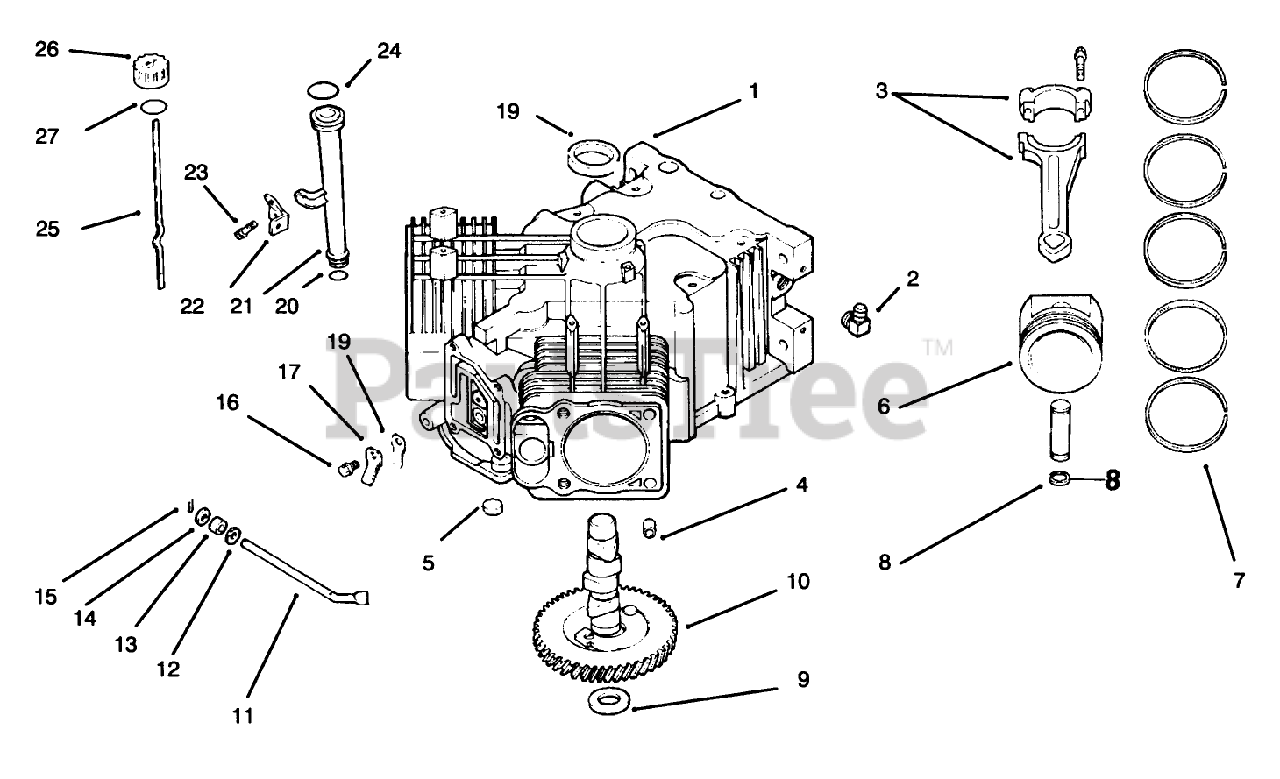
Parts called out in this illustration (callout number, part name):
1	Miniblock
2	Fitting
3	Rod-Connecting (Std)
4	Pin-Dowel
6	Piston w/Ring Set (Std.) (Incl. Ref. # 4-6)
7	Set-Ring (Std)
8	Retainer-Piston Pin
9	Shim-Camshaft
10	Camshaft
11	Shaft-Governor Cross
12	Washer
13	Seal
14	Washer
15	Pin-Hitch
17	Retainer-Reed (Only On: 72103)
18	Beed-Breather (Only On: 72103, 72083)
19	Seal-Oil
20	O-Ring-Lower Fill Tube (Only On: 72042, 72063, 72062, 72043)
21	Tube-Oil Fill (Only On: 72103, 72083)
22	Bracket-Oil Fill Tube (Only On: 72103)
24	O Ring-Upper Fill Tube (Only On: 72103)
25	Dipstick INC 26-27 (Only On: 72103, 72083)
26	Kit-Oil Fill Cap (Incl. Ref. #7)
27	ORing
